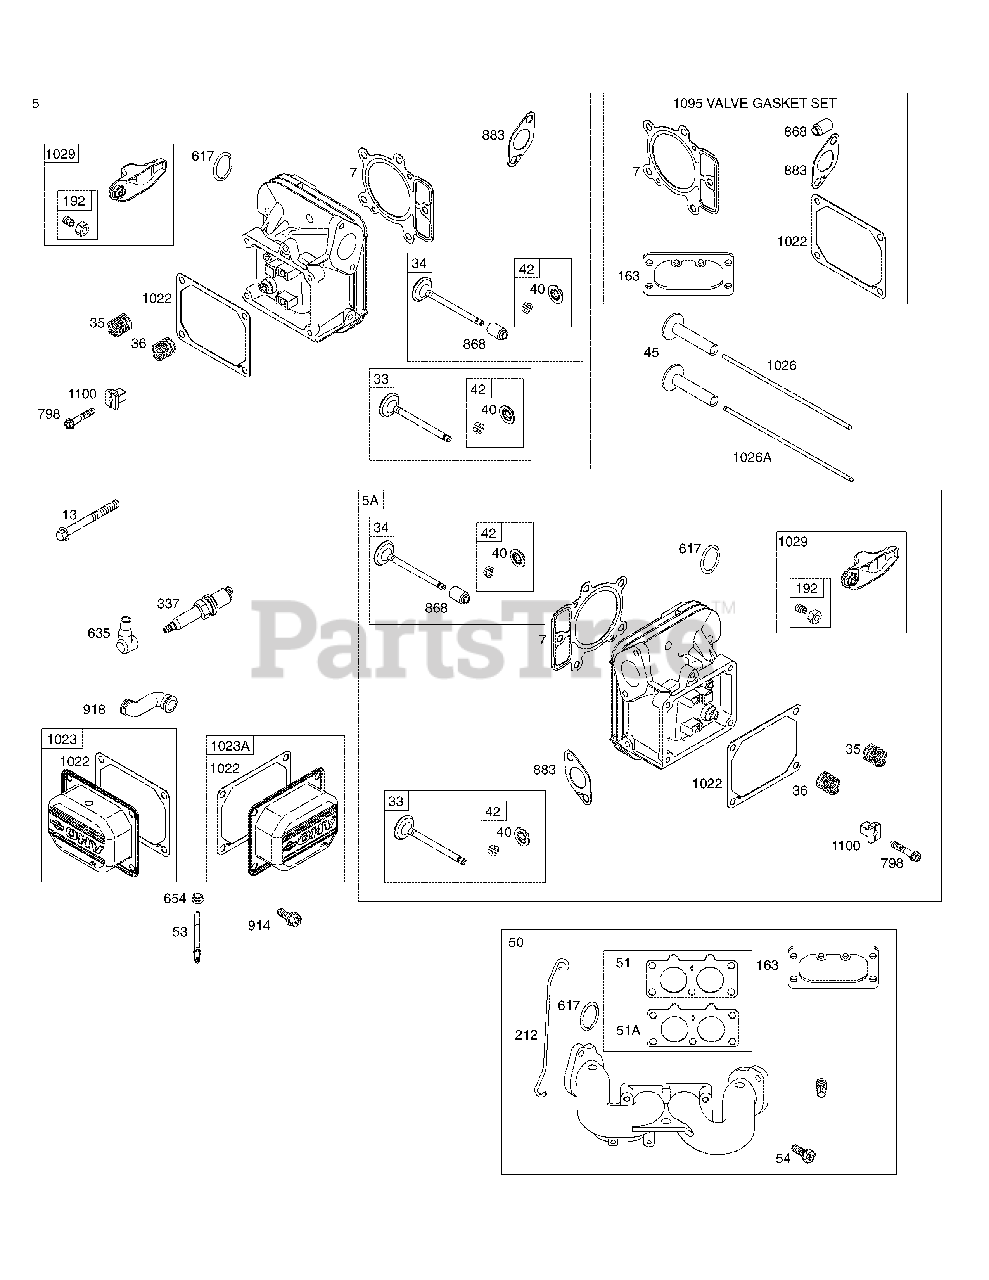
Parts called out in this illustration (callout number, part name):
1	Cylinder Assembly
2	Kit-Bushing/Seal (Magneto Side)
3	Oil Seal (Magneto Side)
4	EngineSump
5	Cylinder Head (Cylinder #1)
5A	Cylinder Head (Cylinder #2)
7	Cylinder Head Gasket
8	Breather Assembly
9	Breather Gasket
10	Screw (Breather Assembly)
11	Breather Tube
12	Crankcase Gasket
13	Screw (Cylinder Head)
15	Oil Drain Plug
16	Crankshaft
20	Oil Seal (PTO Side)
22	Screw (Crankcase Cover/Sump)
23	Flywheel
24	Flywheel Key
25	Piston Assembly (Standard)
25	Piston Assembly (.020" Oversize)
26	Ring Set (Standard)
26	Ring Set (.020" Oversize)
27	Piston Pin Lock
28	Piston Pin
29	Connecting Rod
32	Screw (Connecting Rod)
33	Exhaust Valve
34	Intake Valve
35	Valve Spring (Intake)
36	Valve Spring (Exhaust)
40	Valve Retainer
42	Valve Keeper
45	Valve Tappet
48	Short Block
50	Intake Manifold
51	Intake Gasket
51A	Intake Gasket
53	Stud (Carburetor)
54	Screw (Intake Manifold)
73	Rotating Screen
74	Screw (Rotating Screen)
75	Washer (Flywheel)
95	Screw (Throttle Valve)
98	Idle Speed Kit
104	Float Hinge Pin
105	Float Needle Valve
108	Choke Valve
117	Main Jet (Standard) (Left Jet)
117A	Main Jet (Standard) (Right Jet)
118	Main Jet (High Altitude) (Left Jet)
118A	Main Jet (High Altitude) (Right Jet)
121	Carburetor Overhaul Kit
125	Carburetor
130	Throttle Valve
131	Throttle Shaft Kit
133	Carburetor Float
135	Fuel Transfer Tube
137	Float Bowl Gasket
141	Choke Shaft Kit
142	Carburetor Nozzle
146	Timing Key
150	Nozzle Gasket
163	Air Cleaner Gasket
165	Nut (Ring Gear)
177	O-Ring Seal (Dipstick)
187	Fuel Line (Cut to Required Length)
188	Screw (Control Bracket)
192	Rocker Arm Adjuster
197	Screw (Back Plate)
209	Governor Spring (Yellow/Black)
211	Governed Idle Spring (Orange)
212	Throttle Link
216	Choke Link
217	Choke Return Spring
219	Governor Gear
220	Washer (Governor Gear)
221	Governor Cup
222	Control Bracket
227	Governor Control Lever
231	Screw (Choke Valve)
239	Oil Pressure Switch
240	Fuel Filter
250	Breather Retainer
252	Oil Collector
265	Casing Clamp
267	Screw (Casing Clamp)
276	Sealing Washer (Fuel Solenoid)
278	Washer (Governor Control Lever)
287	Screw (Dipstick Tube)
304	Blower Housing
305	Screw (Blower Housing)
305A	Screw (Blower Housing to Intake Elbow)
306	Cylinder Shield (Cylinder #2)
307	Screw (Cylinder Shield) (1.4-20 x 2.3)
309	Starter Motor
310	Screw (Starter Motor)
332	Nut (Flywheel)
333	Magneto Armature
334	Screw (Magneto Armature)
337	Spark Plug
358	Engine Gasket Set
385	Screw (Fuel Pump)
387	Fuel Pump
404	Washer (Governor Crank)
415	Plug (Oil Pressure Switch)
418	Carburetor Plate
431	Intake Elbow
445	Air Cleaner Cartridge Filter
447	Screw (Air Guide Cover) 10-24 x 7.16)
447A	Screw (Air Guide Cover)
467	Air Cleaner Knob
474	Alternator
501	Regulator
503	Starter Strap
505	Nut (Governor Control Lever)
510	Starter Drive
513	Drive Clutch
523	Dipstick
524	Dipstick Tube Seal
525	Dipstick Tube
526	Screw (Regulator)
544	Starter Armature
552	Governor Crank Bushing
552A	Governor Crank Bushing
562	Screw (Governor Control Lever)
573	Back Plate
579	Nut (Starter Cable)
601	Hose Clamp (Black)
601A	Hose Clamp (Green)
615	Governor Shaft Retainer
616	Governor Crank
617	O-Ring Seal (Intake Manifold) (Red)
628	Screw (Fuel Pump Bracket)
633	Choke Seal/Throttle Shaft
635	Spark Plug Boot
654	Nut (Carburetor)
668	Spacer (Rotating Screen)
668A	Spacer (Rotating Screen)
672	Carburetor Plate Gasket
691	Governor Shaft Seal
695	Screw (Ring Gear)
697	Screw (Drive Cap)
718	Locating Pin
741	Timing Gear
742	E-Ring Retainer (Governor Crank)
750	Screw (Oil Pump Cover)
783	Pinion Gear
788	Fuel Pump Bracket
789	Wiring Harness
798	Screw (Rocker Arm)
803	Starter Housing
847	Dipstick/Tube Assembly
851	Spark Plug Terminal
865	Air Guide Cover (Cylinder #1)
865A	Air Guide Cover (Valley)
868	Valve Seat
877	Alternator Wire/Connector
877A	Alternator Wire/Connector
883	Exhaust Gasket
914	Screw (Rocker Cover)
918	Vacuum Hose
943	O-Ring Seal (Oil Pump Cover)
947	Fuel Solenoid
965	Oil Pump Cover
967	Pre-Cleaner Filter
968	Air Cleaner Cover
975	Float Bowl
987	Throttle Shaft Seal
1005	Flywheel Fan
1013	Oil Filter Nipple
1017	Oil Pump Screen
1022	Rocker Cover Gasket
1023	Rocker Cover (Cylinder #1)
1023A	Rocker Cover (Cylinder #2)
1026	Push Rod (Exhaust)
1026A	Push Rod (Intake)
1027	Oil Filter
1029	Rocker Arm
1036	Emissions Label
1040	Trim Plate
1051	Retaining Ring (Starter Drive)
1058	Operator's Manual
1059	Screw/Washer Kit (Alternator)
1070	Screw (Flywheel Fan)
1090	Brush Retainer
1095	Valve Gasket Set
1100	Rocker Arm Pivot
1119	Screw (Alternator)
1124	O-Ring Seal (Fuel Transfer Tube)
1124A	O-Ring Seal (Fuel Transfer Tube)
1126	Screw (Fuel Transfer Tube)
1127	Screw (Fuel Bowl)
1128	Screw (Carburetor Nozzle)
1169	Screw (Carburetor Plate)
1329	Replacement Engine
